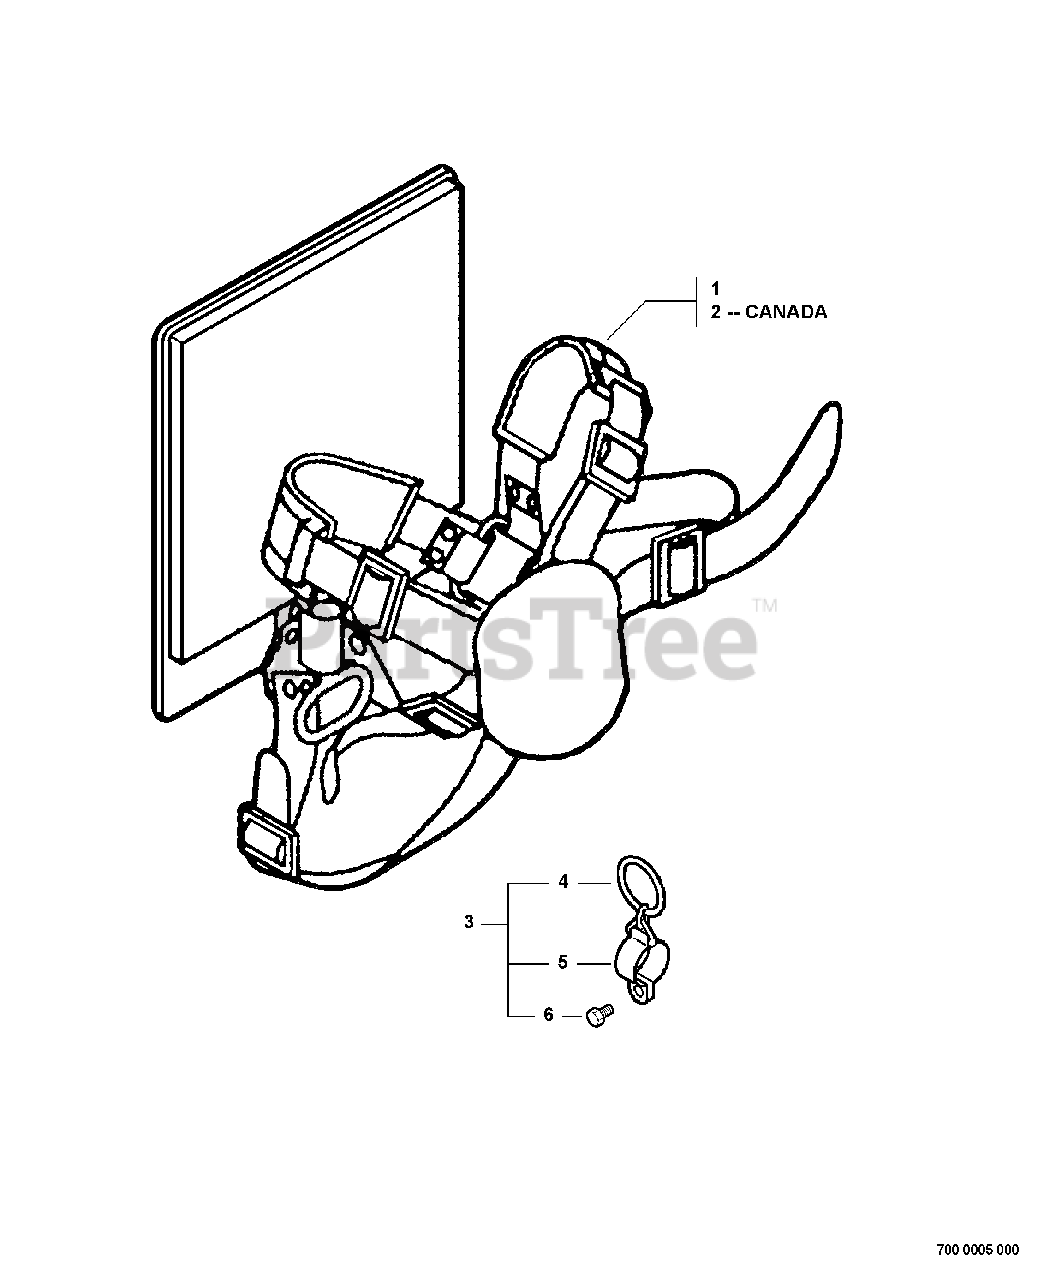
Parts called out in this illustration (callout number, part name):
1	HARNESS, SHOULDER
2	HARNESS, SHOULDER
3	HANGER ASSY, HARNESS
4	RING, HARNESS
5	HANGER, HARNESS
6	SCREW - 5×12
